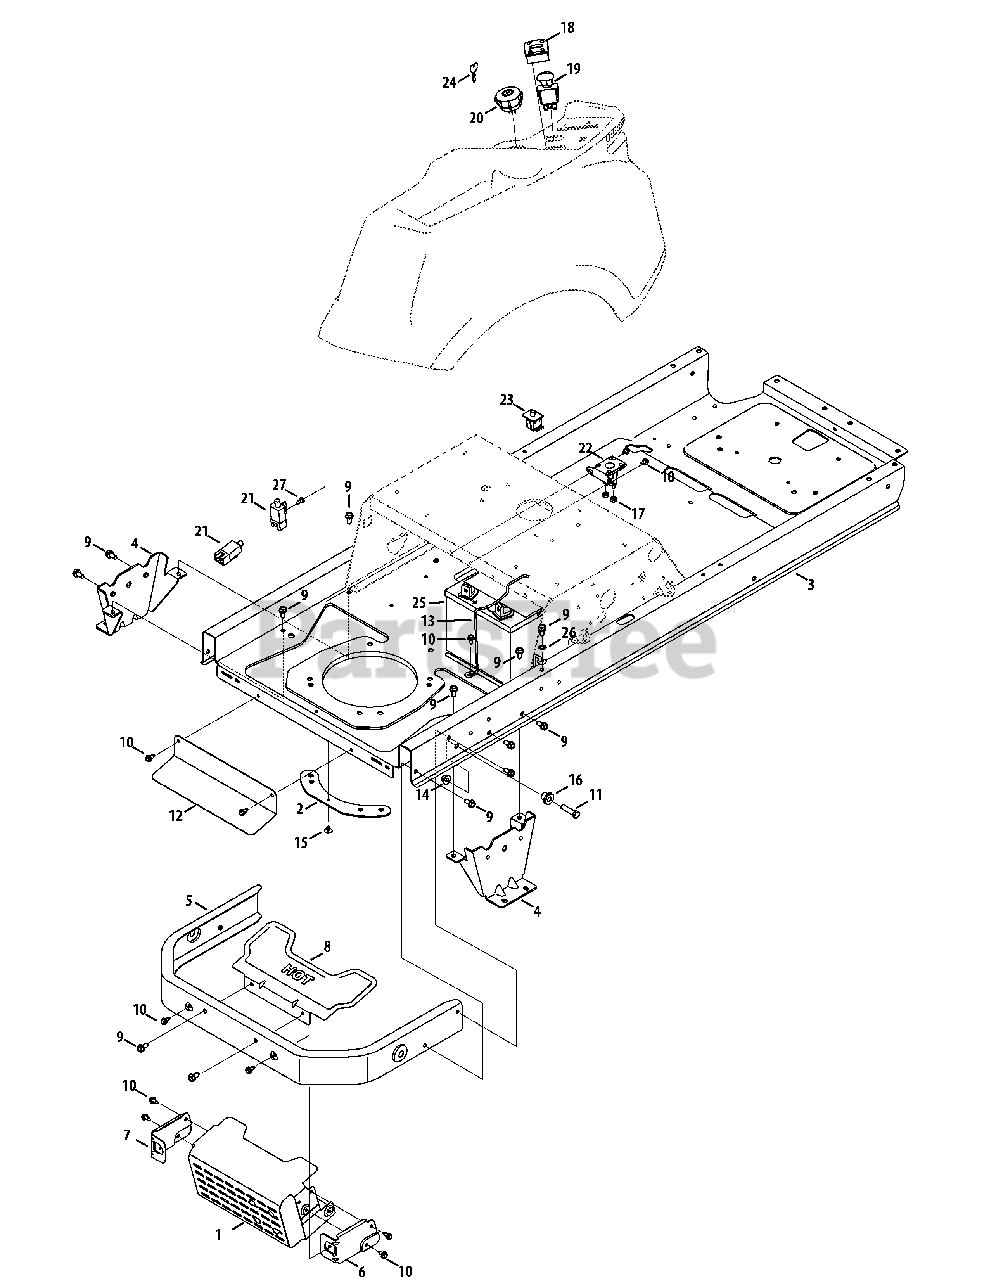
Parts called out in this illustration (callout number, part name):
1	Muffler Shield Assembly
2	Retainer Plate
3	Frame, RZT Yellow
3	Bracket, Transmission Mounting Front
3	Bracket, Spring Mounting
4	Transmission Mounting Bracket
5	Rear Bumper
6	Muffler Mounting Shield Bracket, RH
7	Muffler Mounting Shield Bracket, LH
8	Muffler Shield
9	Hex Washer Screw, 5/16-18 x .750
10	Hex Washer Screw, 1/4-20 x .625
11	Hex Screw, 3/8-16 x 1.25
12	Lower Heat Shield
14	Flange Lock Nut, 3/8-16
15	Clip, .250 Dia. x .500 LG
16	Shoulder Spacer, .38 x 1.0 x .70
17	Flange Lock Nut, 1/4-20
18	Hour Meter/Service Minder
19	Electric PTO Switch
20	Key Switch
21	Interlock Switch
22	Solenoid
23	Seat Switch
24	Key, Assembly
26	Lock Washer, 5/16
27	Shoulder Screw, #10-32 x .500
